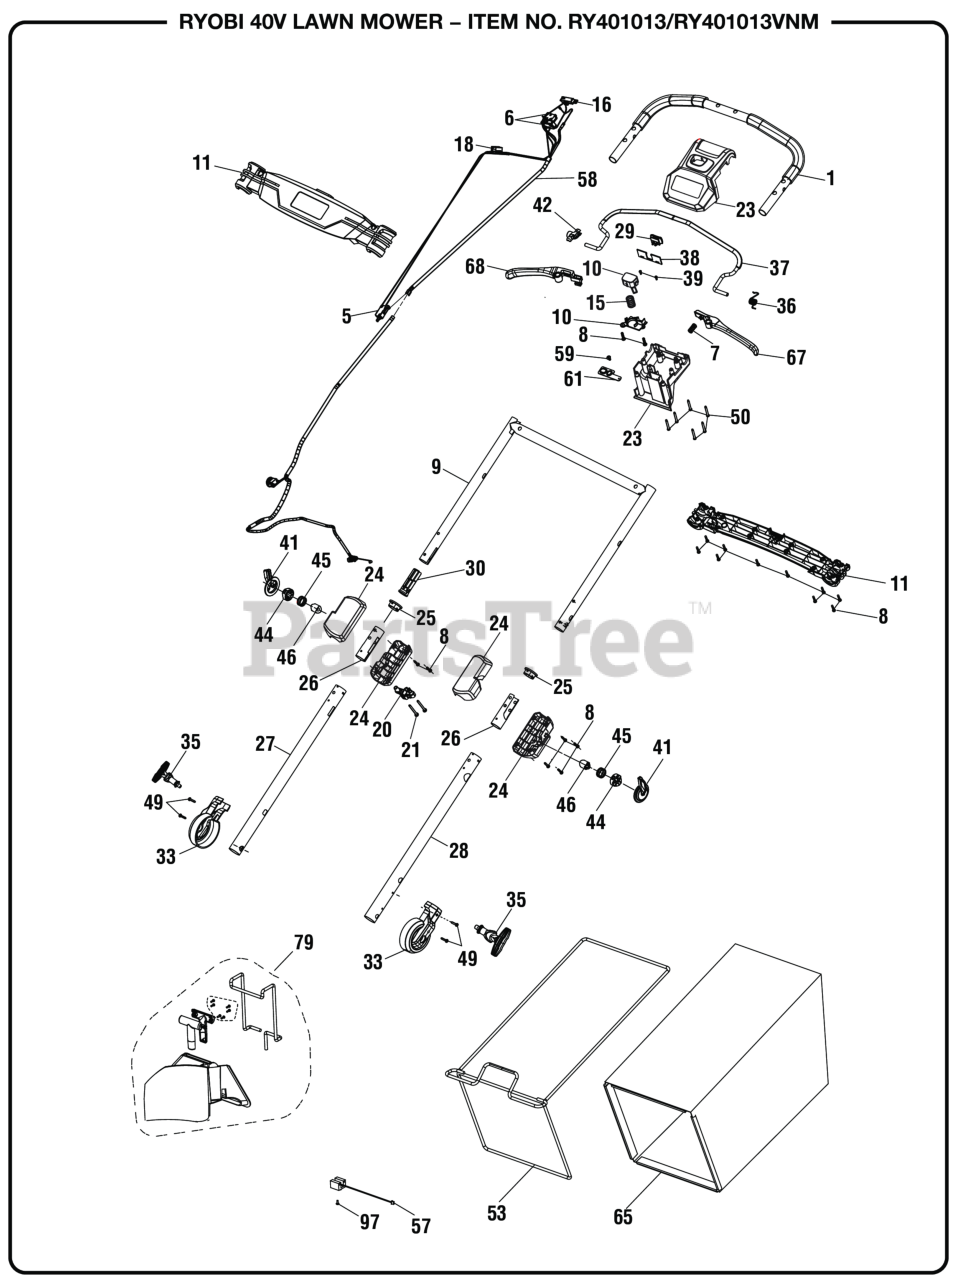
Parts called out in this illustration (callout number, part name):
1	Upper Handle Assembly
6	On/Off Switch
7	Compression Spring
8	Screw (M4 x 18 mm, T20 Torx Pan Hd.)
9	UPPER HANDLE TUBE W/ LABEL
10	Safety Button Assembly
11	Upper Handle Housing Assembly
15	Safety Button Spring
16	Variable Switch
18	Stop Switch (Momentary Contact)
20	Press Plate
21	Screw (M4 x 38 mm)
23	UPPER HANDLE SUPPORT ASSEMBLY W/ LABEL
24	Handle Latch Assembly
25	Handle Tube Bushing
26	Handle Tube Bushing (Small)
27	Tube (Right)
28	Tube (Left)
29	Thumb Pad
30	Switch Plug Housing
31	Front Housing Handle Latch (Left)
32	Rear Housing Handle Latch (Left)
33	HINGE SHROUD
34	Rear Housing Handle Latch (Right)
35	Spring Pin Adjustment Assembly
36	Torsion Spring
37	Bail Handle (Power Lever)
38	Dust Shield
39	Screw (M3 x 8 mm, Pan Hd., Pan Hd)
41	Side Handle Latch
42	Actuator Switch
44	Disc Holder
45	Handle Compression Spring
46	Side Compression Disc
49	Screw (M4 x 20 mm, T20 Torx Pan Hd. S.T.)
50	Screw (M4-18 x 30 mm, T15 Torx Soc. Hd.)
53	Bag Frame
57	SENSOR SWITCH FOR GRASS BAG
58	Inner Wire and Plug Assembly
59	Screw (M4x 7 mm, T20 Torx Hd)
61	Cable Bracket
65	21 in. Grass Bag
67	TRIGGER ASSEMBLY
79	Mulching Plug Assembly (Inc. Hangtag)
97	Screw w/Washer (M4 x 10 mm, T20 Torx Button Hd.)
